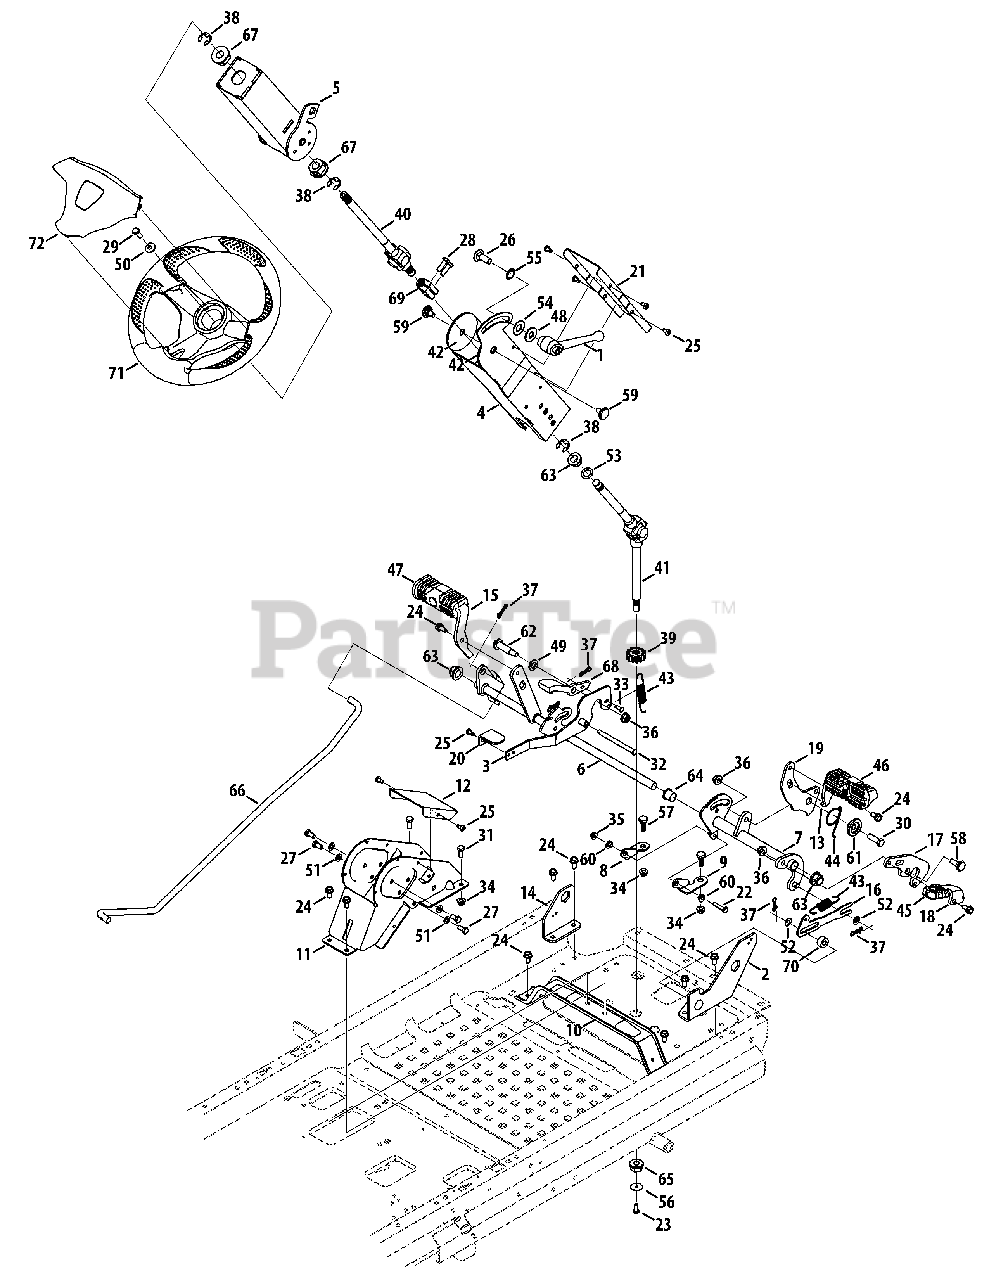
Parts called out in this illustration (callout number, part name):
1	Steering Column Adjustment Lever
2	Support Bracket Assembly, RH
3	Brake Pedal Assembly
4	Lower Column Assembly
5	Upper Column Assembly
6	Brake Pedal Assembly
7	Drive Pedal Assembly
8	Speed Bracket, LH
9	Speed Bracket, RH
10	Steering Support Bracket
11	Lower Steering Wheel Column
12	Lower Column Cover
13	Drive Pedal
14	Support Bracket, LH
15	Brake Pedal
16	Return to Neutral Link
17	Reverse Pedal Bracket
18	Reverse Pedal
19	Forward pedal Bracket
20	Tilt Steering Pedal
21	Steering Column Cover
22	Hex Head Screw, 1/4-20 x 1.25
23	Hex Head Screw, 1/4-20 x .625
24	SCREW 5/16-18 x .750
25	Screw, 1/4-20 x .5
26	Carriage Bolt, 1/2-13 x 1.25
27	Hex Screw, 5/16-18 x .625
28	Hex Cap Screw, 5/16-18 x 1.00
29	Hex Screw, 5/16-24 x.875
30	Hex Screw, 3/8-16 x 1.25
31	SCREW 5/16-18 x .75 GR5
32	Clevis Pin, 5/16 x 4.135
33	Clevis Pin, .224 Dia. x .625
34	Flange Lock Nut, 5/16-18
35	Flange Lock Nut, 1/4-20
36	Flange Lock Nut, 3/8-16
37	Bow-Tie Cotter Pin, 72
38	E-Ring, .750
39	14-Tooth Spur Gear
40	Upper Steering Shaft
41	Lower Steering Shaft
42	Column Wear Plate
43	Extension Spring, .70 OD x 3.035 LG
44	Torsion Spring, 1.00 ID x .22
45	Reverse Pedal Pad
46	Forward Pedal Pad
47	Brake Pedal Pad
48	Washer, Flat, .531 x 1.25 x .100
49	Flat Washer, .535 x .930 x .090
50	Bell Washer, .340 x .872 x .060
51	Flat Washer, .330 x .630 x .064
52	Thrust Washer, .375 x .700 x .030
53	Flat Washer, .634 x 1.00 x .040
54	Washer, .640 x 1.25 x .050
55	Lock Washer, 17 x 23.8 x 1.95
56	Flat Washer, .265 x 1.00 x .030
57	Shoulder Screw, 5/16-18 x .437 x .268
58	Shoulder Bolt, 3/8-16 x .500 x .270
59	Shoulder Screw, 3/8-16 x .625 x .175
60	SHOULDER SPACER
61	SHOULDER SPACER 1.5X.38X.38
62	Shoulder Screw, 3/8-16 x .496 x 1.445
63	Hex Flange Bearing
64	NYLINER BEARING
65	Hex Flange Bearing, 7/16
66	Front Brake Rod
67	Flange Bearing, .63 ID x 1.50
68	Cruise Latch
69	Steering Shaft Coupling
70	Spacer, .385 ID x .875 OD x .458
71	Steering Wheel Assembly
72	Steering Wheel Cover
